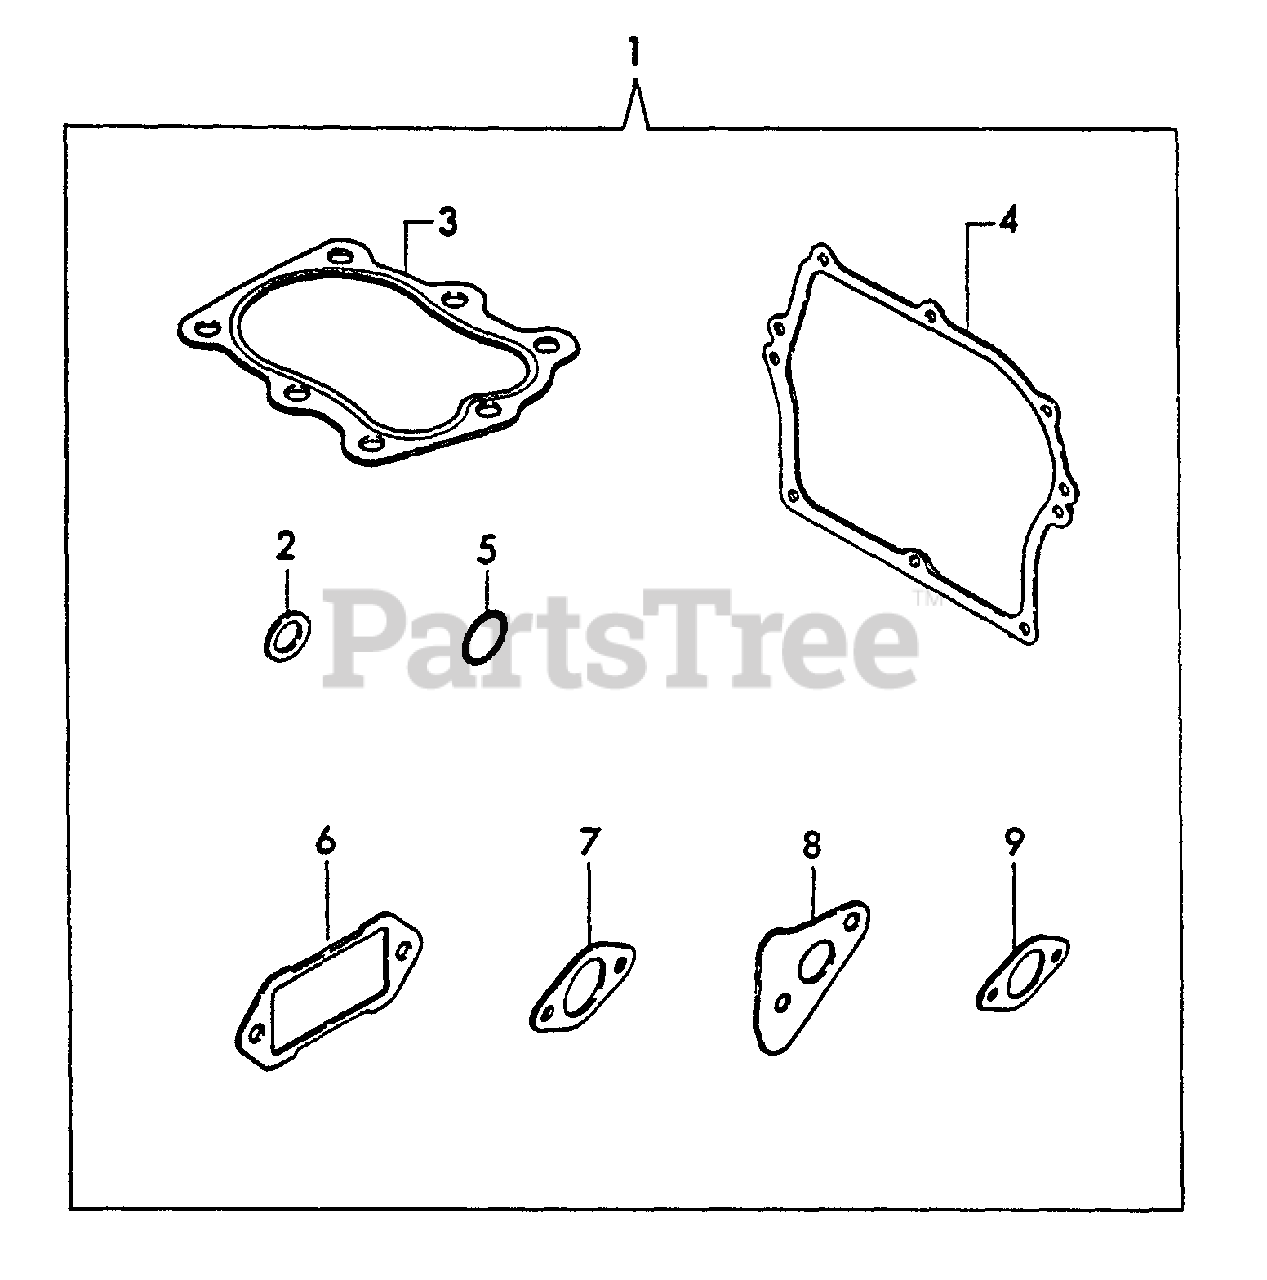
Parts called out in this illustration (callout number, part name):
1	GASKET KIT
2	GASKET
3	GASKET, CYLINDER
4	GASKET, SIDE COVER
5	O-RING 1A P-18.0
6	GASKET
7	GASKET, INTAKE
8	GASKET, EXHAUST
9	GASKET, EXHAUST
